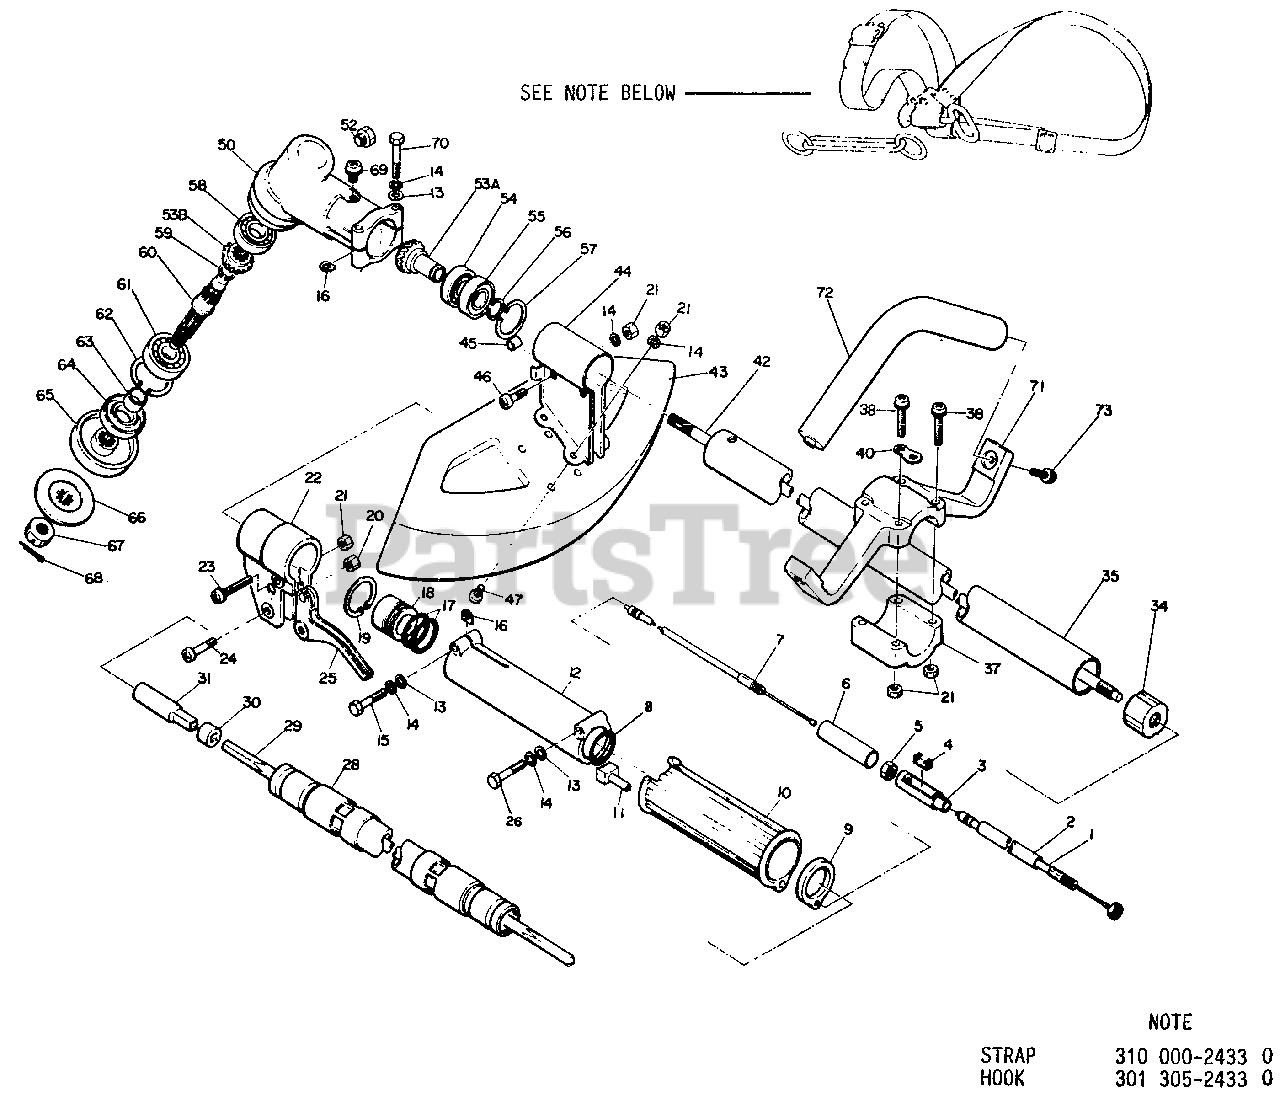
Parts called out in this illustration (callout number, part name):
1	CABLE, THROTTLE
2	SLEEVE
3	CONNECTOR, CABLE
4	CONNECTOR
5	LOCKNUT - 6
7	CABLE, THROTTLE
8	O-RING - 18
10	GRIP
11	GUIDE, CABLE
12	CONNECTOR
13	WASHER - 5
14	LOCKWASHER - 5
14	LOCKWASHER - 3
15	BOLT - 5X25
17	O-RING - 22
18	STOPPER
19	RING, RETAINING - 28
20	LOCKNUT - 5
22	BRACKET, TRIGGER
23	SCREW - 5X28
24	SCREW - 5X30
25	TRIGGER, THROTTLE
28	LINER - FLEXIBLE
29	DRIVESHAFT - FLEXIBLE
30	SPACER
31	CONNECTOR, SHAFT
34	STOPPER
35	MAIN PIPE ASSY
37	BRACKET, HANDLE
38	SCREW - 5X35
40	HANGER
41	HARNESS ASSY
42	DRIVESHAFT
44	BRACKET, SHIELD
46	SCREW - 5X18
47	SCREW - 5X8
50	CASE, GEAR
52	BOLT - 8X8
53	GEAR SET
53A	GEAR SET
53B	GEAR SET
54	BEARING, BALL - 6001
55	BEARING, BALL - 6001
56	RING, RETAINING - 12
57	RING, RETAINING - 28
58	BEARING, BALL - 6000
59	RING, RETAINING - 12
60	GEAR - SHAFT
61	BEARING, BALL - 6201
62	RING, RETAINING - 32
64	SEAL, OIL
65	ADAPTOR, BLADE - UPPER
66	ADAPTOR, BLADE - LOWER
67	NUT - 10 -- LEFT HAND
68	PIN, SPLIT - 2X22
69	SCREW - 5X10
70	BOLT - 5X30
71	BRACKET, HANDLE - UPPER
72	HANDLE - FRONT
73	SCREW - 5X14
